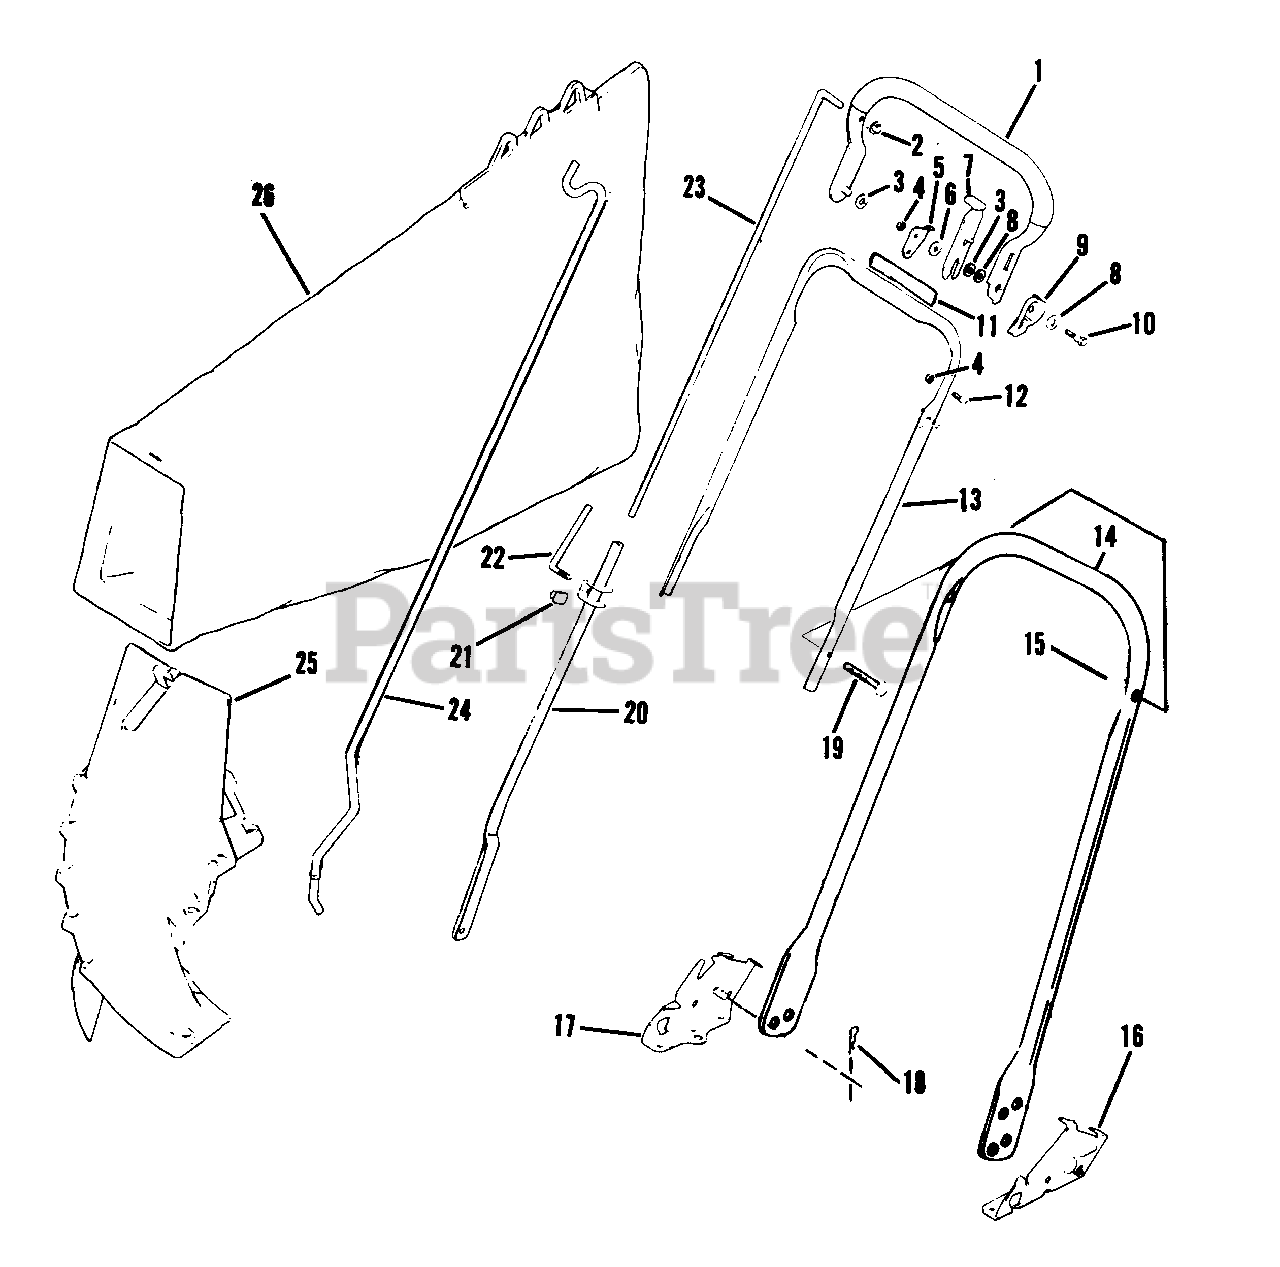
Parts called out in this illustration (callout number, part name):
1	Handle & Grip Assembly
2	Palnut
3	Washer
4	Nut-Lock
5	Stop-Handle
6	Washer
7	Lever-Lockout
8	Washer
9	Guard-Lever
10	Bolt-Shoulder
11	Decal
12	Screw-Stop
13	Handle-Center
14	Handle Section-Bottom
15	Nut-Lock
16	Bracket-Handle L.H.
17	Bracket-Handle R.H.
18	Hair Pin
19	Bolt
20	Control Lever Assembly
21	Nut
22	Screw
23	Control Rod
24	Rod-Grass Bag
25	Chute Assembly
26	Bag Assembly
